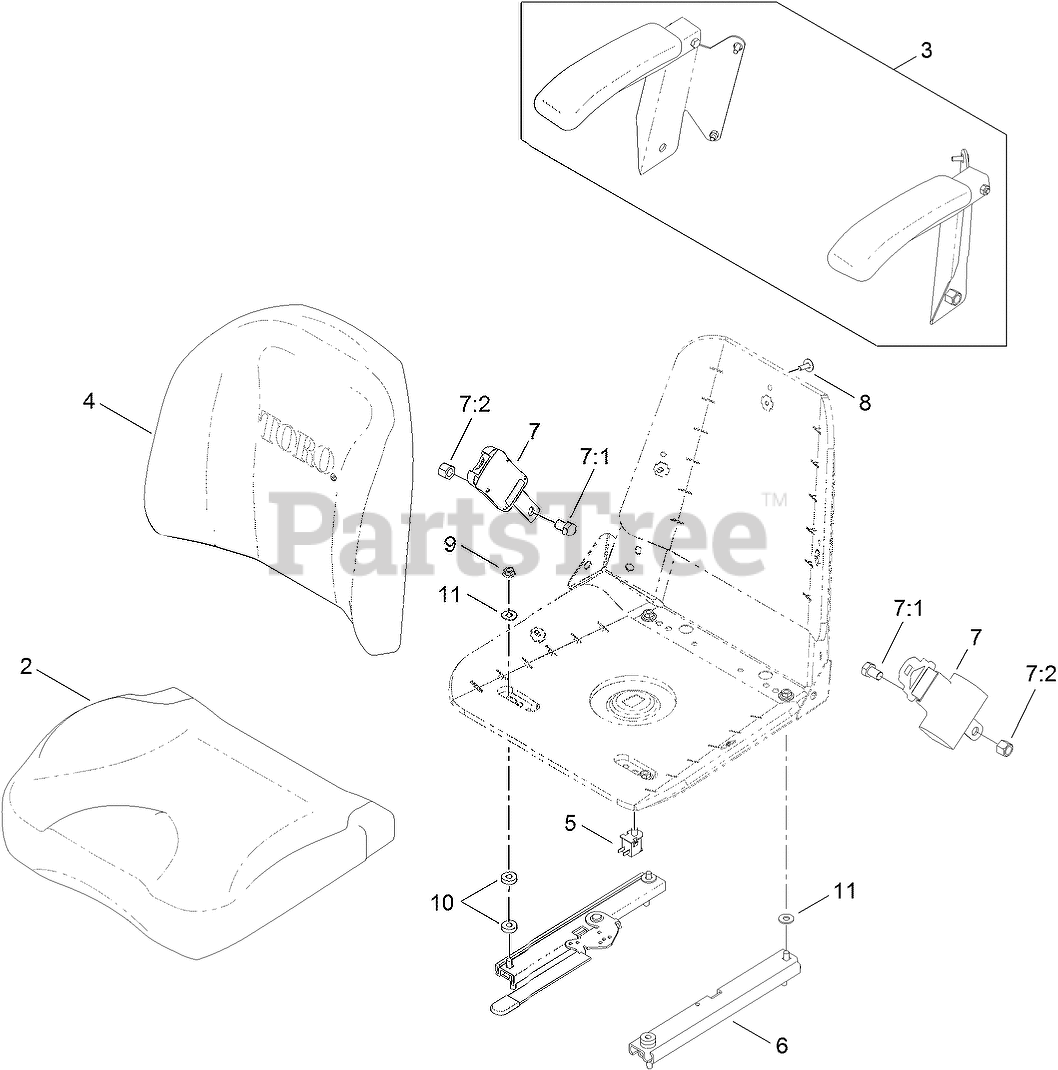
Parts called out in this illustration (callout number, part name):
2	CUSHION-SEAT, BOTTOM
3	ARMREST KIT
4	CUSHION-SEAT, BACK
5	SWITCH-BAIL
6	TRACK ASM
7	SEAT BELT KIT
7:1	SCREW-HH
7:2	NUT-LOCK, NI
8	BOLT-SEAT
9	NUT-HF
10	SPACER-PIN, MOUNTING
11	WASHER-FLAT
